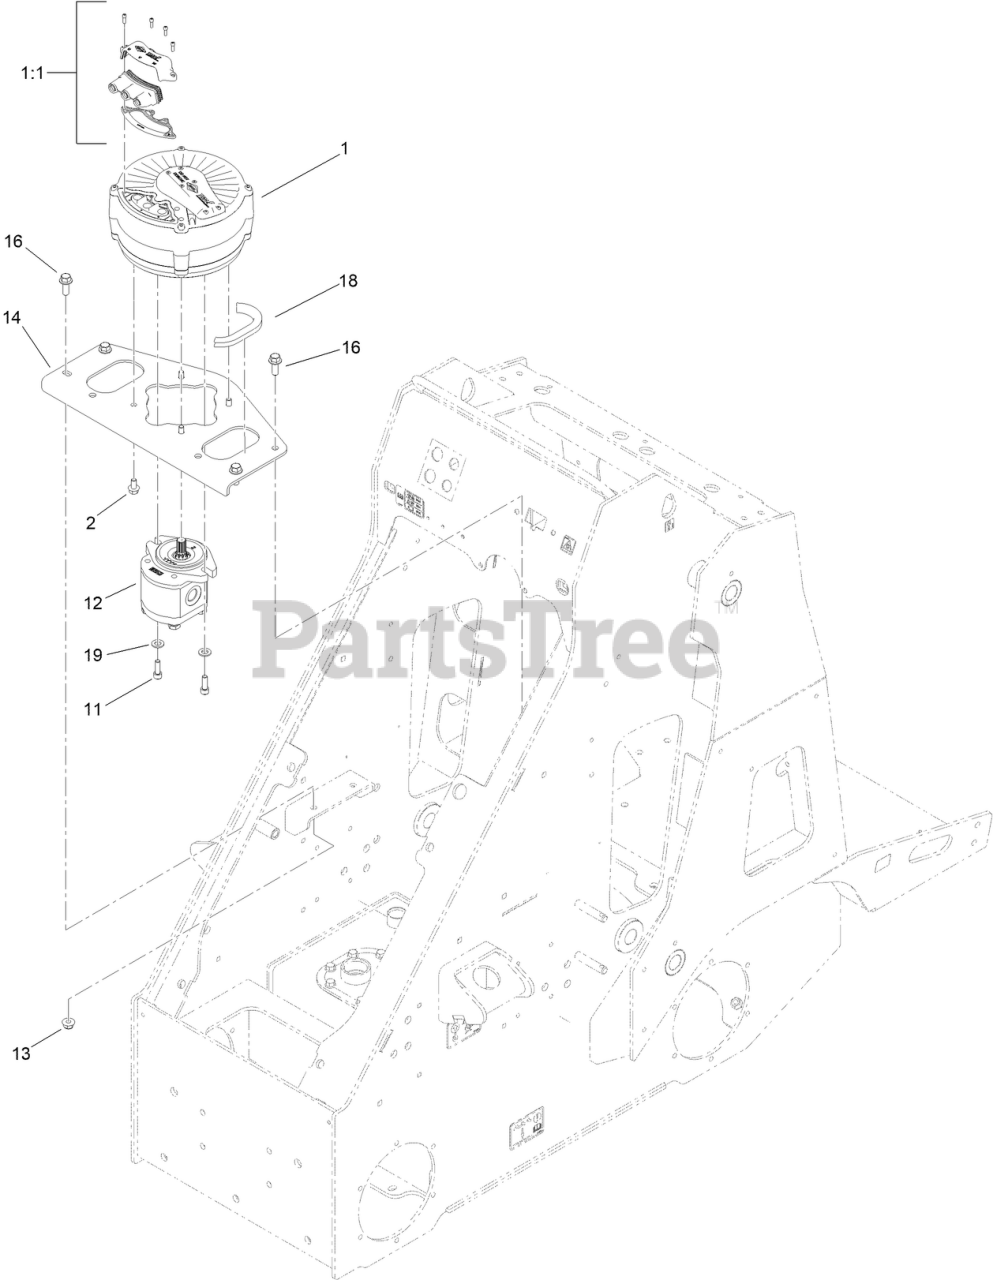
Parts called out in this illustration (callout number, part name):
1	MOTOR/GEN
1:1	TERMINAL ACCESSORY PACK
2	SCREW-HHF
11	SCREW-HSH
12	PUMP-HYDRAULIC
13	NUT-HF, NI
14	PLATE-MOUNT,MOTOR
16	SCREW-HHF
18	TRIM-SEAL
19	WASHER-FLAT
